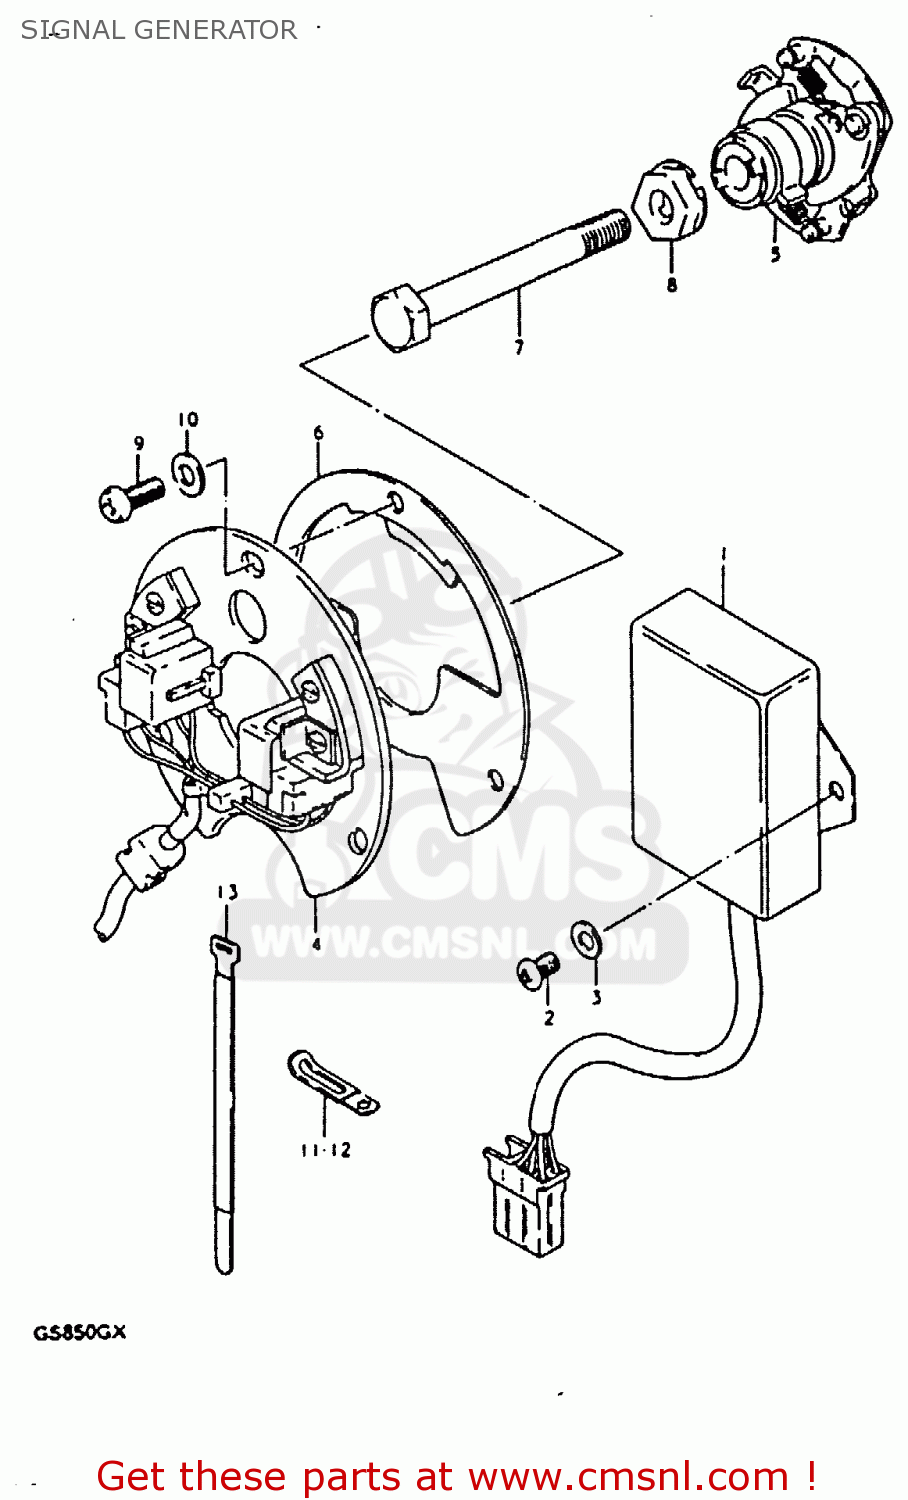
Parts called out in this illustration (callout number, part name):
1	IGNITER UNIT
2	SCREW
3	WASHER
4	SIGNAL GENERATOR ASSEMBLY
5	GOVERNOR ASSEMBLY
6	PLATE,TIMING
7	BOLT
8	WASHER
9	SCREW(5X12)
10	WASHER
11	CLAMP L:35
12	CLAMP
13	CLAMP
